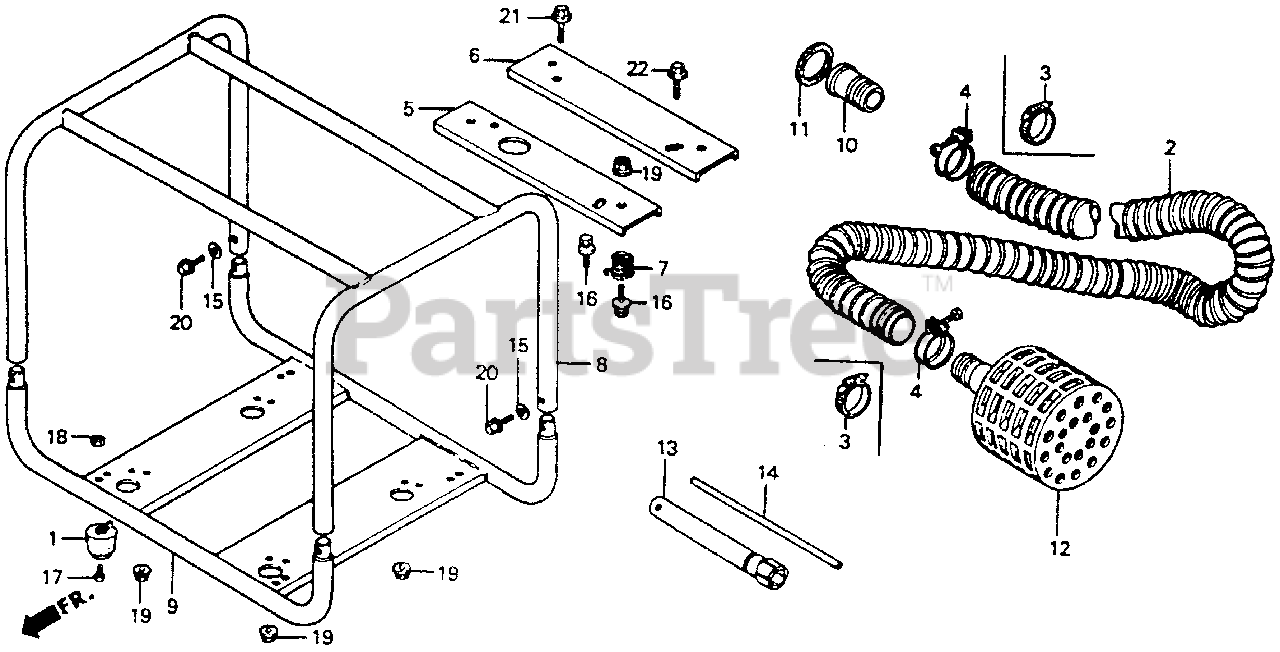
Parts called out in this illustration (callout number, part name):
1	RUBBER (LOWER)
2	HOSE, SUCTION
3	BAND, HOSE
5	STAY A, MOUNTING
6	STAY B, MOUNTING
7	SPRING, MOUNT
8	FRAME (UPPER)
9	FRAME (LOWER)
10	COUPLING, HOSE
11	GASKET, HOSE COUPLING
12	STRAINER Use up to Frame SN 1582885.
12	STRAINER
13	WRENCH, SPARK PLUG
14	HANDLE, BOX WRENCH
15	WASHER, FRAME JOINT
16	BOLT-WASHER (8X20)
17	SCREW, PAN (6X10)
18	NUT, HEX. (6MM)
19	NUT, FLANGE (8MM)
20	BOLT, FLANGE (8X18)
21	BOLT, FLANGE (8X25)
22	BOLT, FLANGE (8X28)
